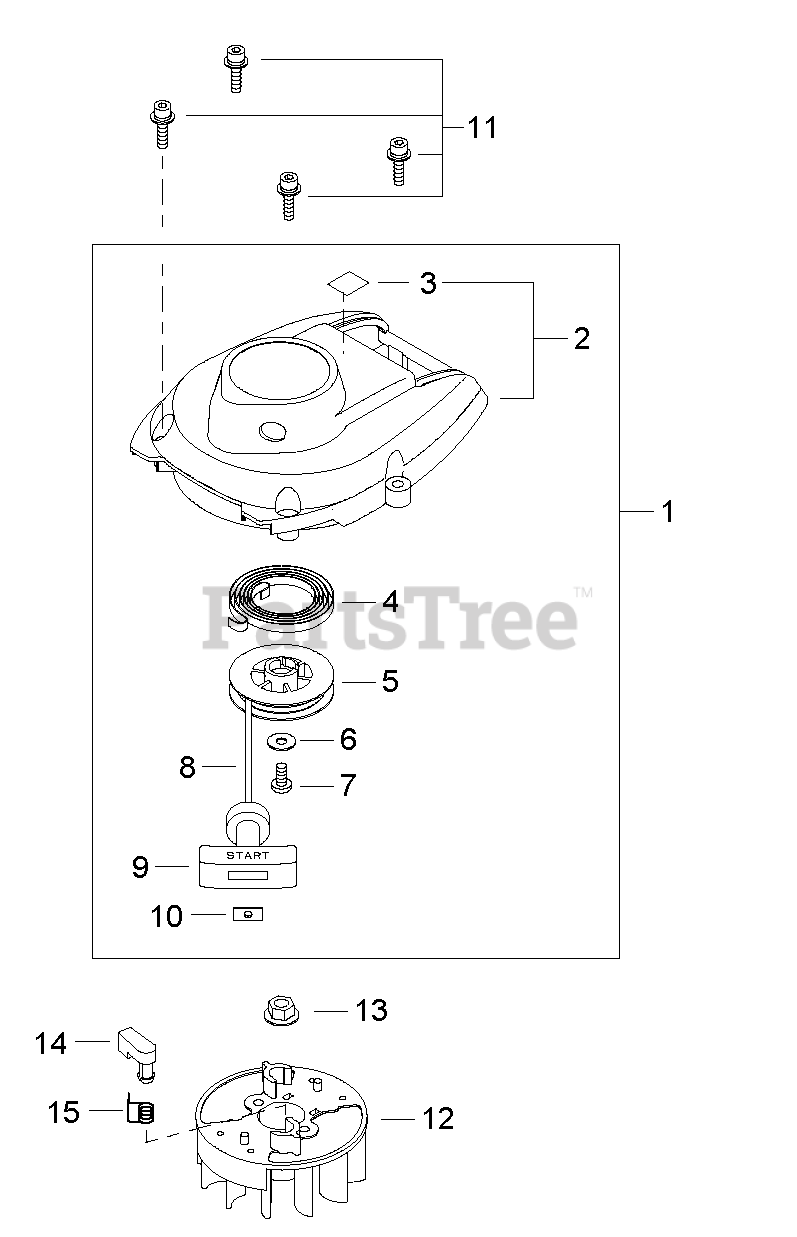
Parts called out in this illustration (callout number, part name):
1	STARTER ASSY, RECOIL
2	CASE ASSY, RECOIL STARTER
3	LABEL, CAUTION - HOT
4	SPRING, RECOIL
5	REEL, ROPE
6	WASHER 5
7	SCREW 5
8	ROPE, STARTER
9	GRIP, STARTER
10	RETAINER, ROPE
11	BOLT, ADHESIVE M5×20
12	FLYWHEEL
15	SPRING, TORSION
